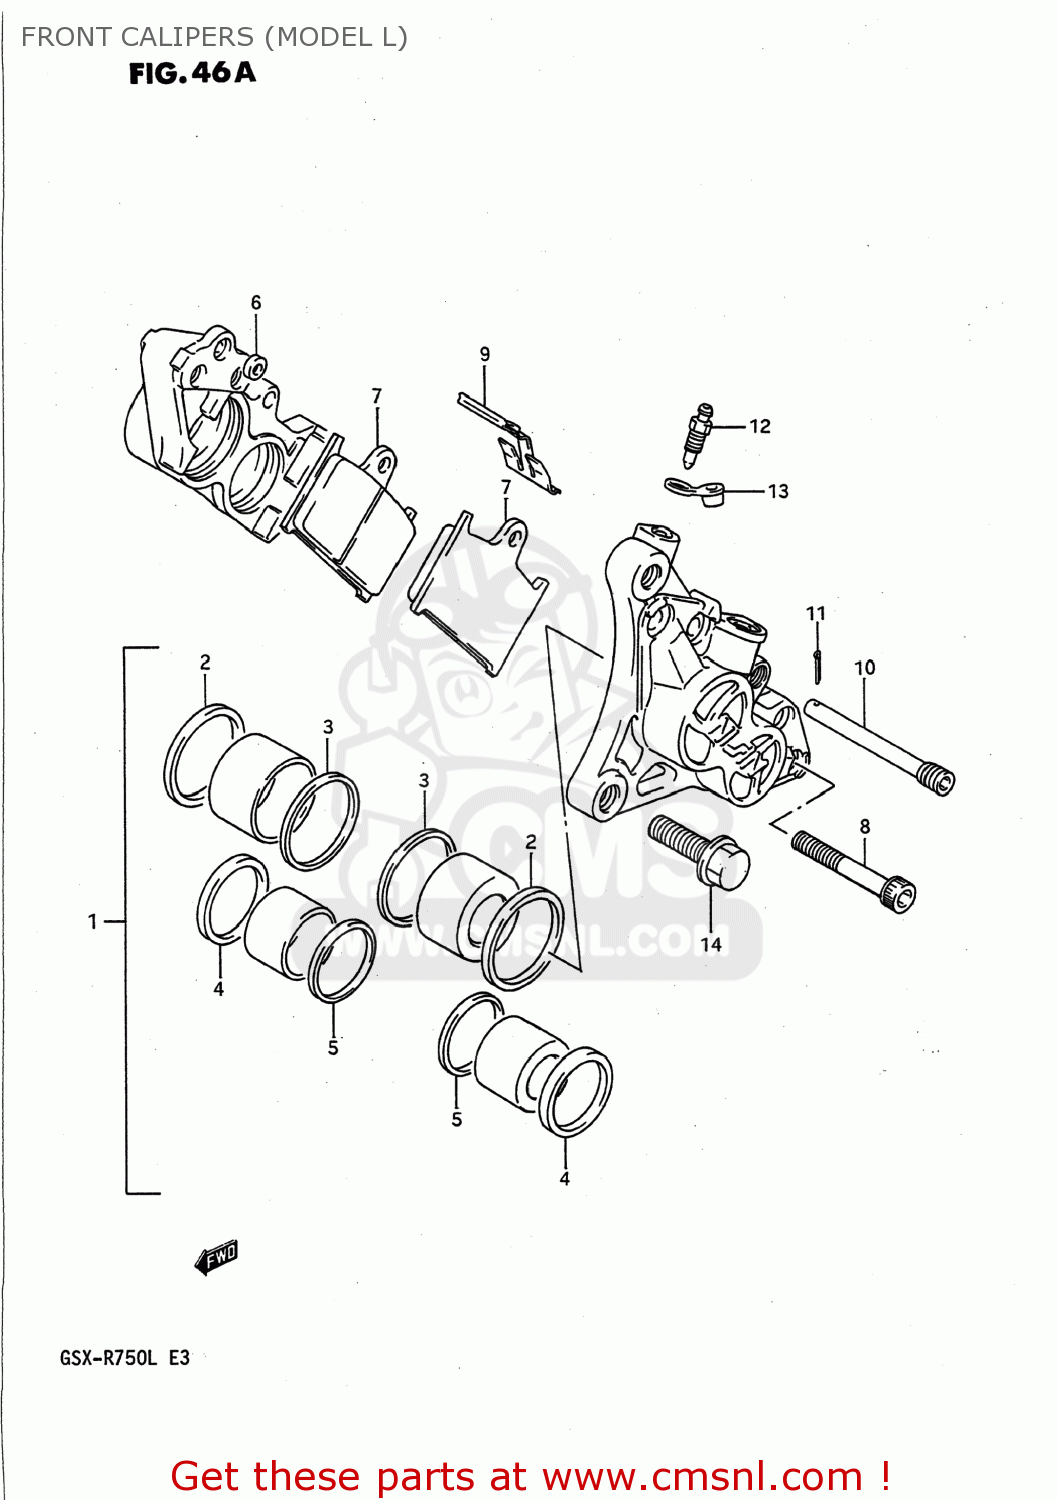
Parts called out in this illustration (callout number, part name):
1	PISTON SET
2	SEAL,PISTON
3	BOOT,PISTON
4	SEAL,PISTON
5	SEAL
6	SEAL
7	PAD,BRAKE
8	BOLT
9	SPRING
10	PIN,HANGER
11	COTTER PIN
12	BLEEDER
13	CAP,BLEEDER
14	BOLT 10X30
